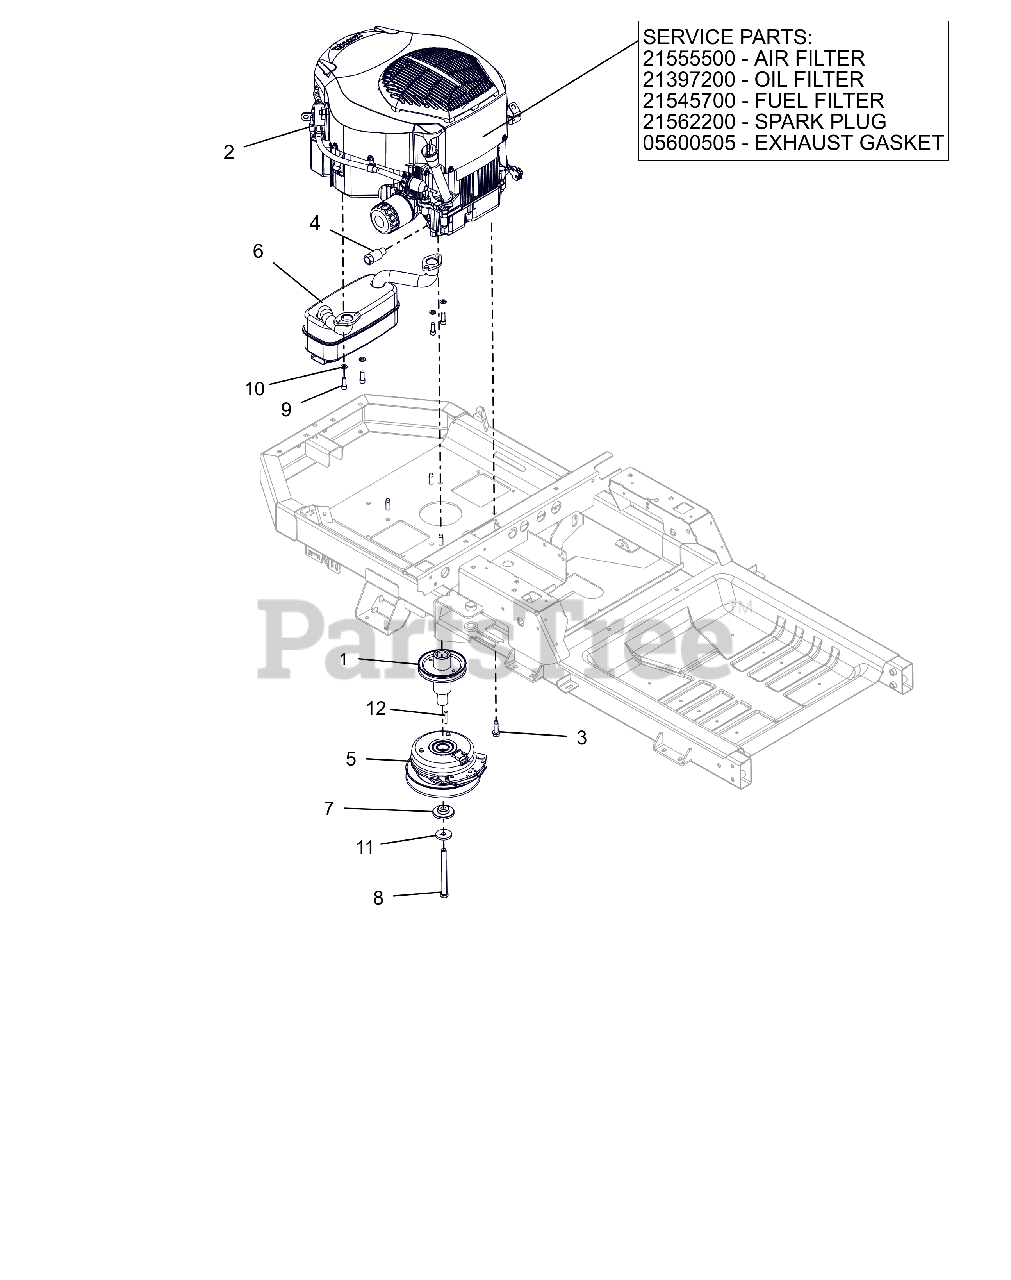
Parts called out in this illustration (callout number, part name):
1	WLDMT, DRIVE SHEAVE (LG XL)CZC
2	ENGINE, KOHLER 24HP TWIN
2	AIR CLEANER, KOHLER
2	FILTER, OIL - KOH CV20
2	FILTER-FUEL KOHLER COURAGE PRO
2	PLUG, SPARK (RFI)
2	GASKET, MUFFLER COURAGE TWIN
3	SCR,TAP .375-16X1.25HWH TR ZCC
4	DRAIN, OIL
5	CLUTCH,105FTLB MONOPOLE 6.83"
6	MUFFLER - KOHLER
7	BSHG-FLG .469X1.06X.574X2.0
8	BLT-HEX.438-20X5 GR8 YZ NYTORQ
9	SCR-CAP .31-18X.88 S/HD G8 ZCC
10	WSHR,LK-REG .312X.078 ZCC
11	WASHER, 7/16" SPRING DISK
12	KEY-SQ .25 X 1.25 X .25 SAE
